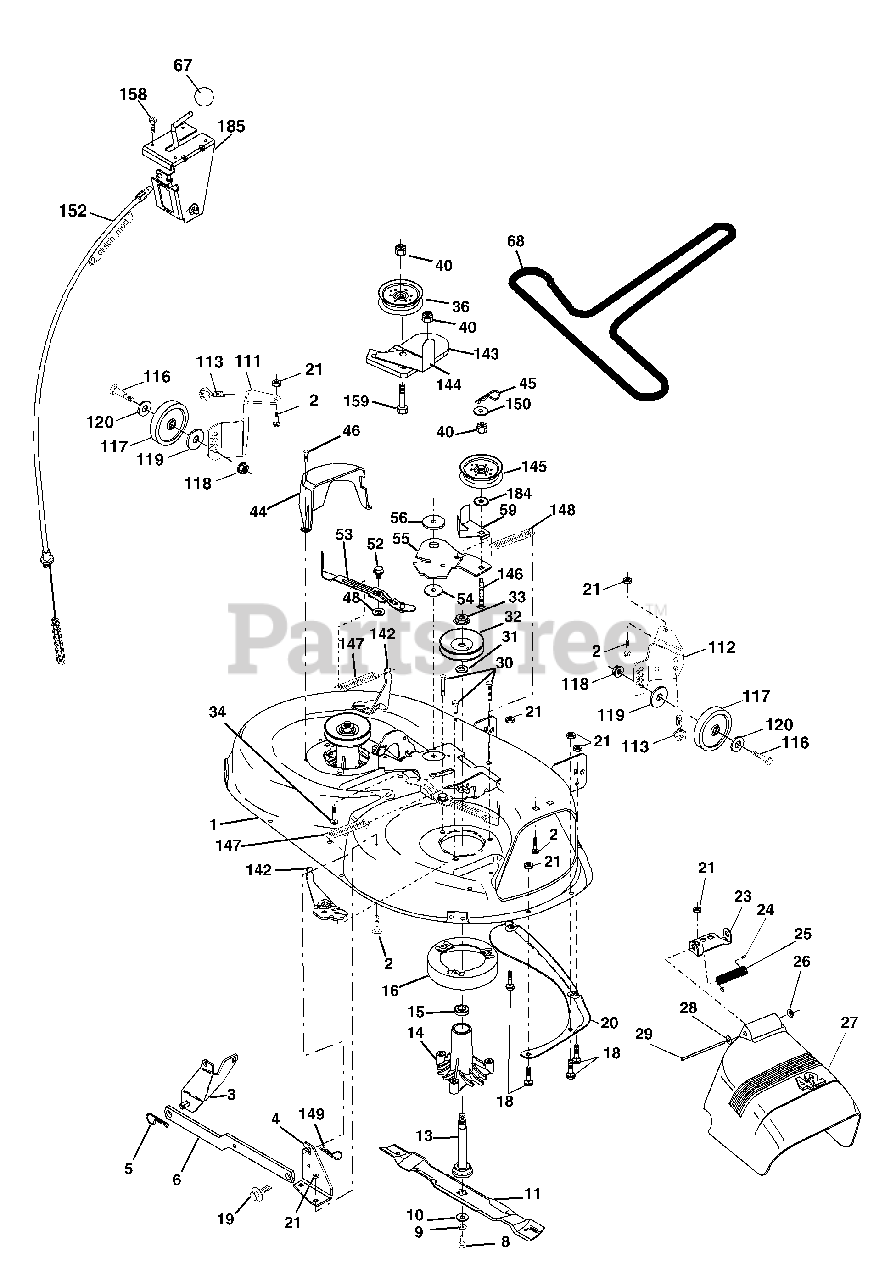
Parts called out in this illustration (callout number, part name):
1	Mower Deck Assembly, 42"
2	Bolt
3	Bracket Asm Fr. Sway Bar 3/42
4	Bracket Asm Deck 42" Sway Bar
5	Retainer Spring
6	Bar Sway Deck
8	Bolt 3/8-24 x 25 Gr. 8 patched
9	Washer, Lock
10	Washer, Hardened
11	Blade, 42" Mulching Std
11	Blade, 42" Mulching Premium
11	Blade, 42" Hi-Lift
13	Shaft Assembly, Mandrel, Vented
14	Housing, Mandrel, Vented
15	Bearing, Ball, Mandrel
16	Stripper, Mandrel Deck
18	Bolt, Carriage 5/16-18 x 5/8
19	Bolt, Shoulder
20	Baffle, Vortex
21	Nut
23	Bracket, Deflector Mower 42"
24	Cap, Sleeve 80 x 112 Blk Mower
25	Spring, Torsion, Deflector 2 52
26	Nut, Push Phos & Oil
27	Shield, Deflector 42" Blk
28	Washer 11/32 x 5/8 x 16 Ga.
29	Rod, Hinge 42" 6 75 W/G
30	Screw Thdrol Washer Head
31	Washer, Spacer Mower Vented
32	Pulley, Mandrel
33	Nut, Toplock 9/16 Flange
34	Bolt
36	Pulley, Idler, Flat
37	Washer 13/32 x 13/16 x 16 Ga.
44	Guard, Mandrel, LH
45	Retainer
46	Screw, Thdrol 1/4-20 x 5/8 T
48	Washer, Hardened
52	Bolt, Shoulder 5/16-18 unc
53	Arm Assembly, Pad, Brake
54	Washer, Hardened
55	Arm, Idler
56	Spacer, Retainer
59	Guard TUV Idler
67	Knob
68	V-Belt, 42" Mower
111	Bracket Wheel Gauge LH
112	Bracket Wheel Gauge RH
113	Bolt 5/16-18
116	Bolt Shoulder
117	Wheel Gauge
118	Nut Centerlock 3/8-16
119	Washer 3/8 x 7/8 x 14 Ga.
120	Washer 17/32 x 15/16 x 12 Ga.
142	Arm Spring Brake Mower
143	Bracket Arm Idler 42"
144	Keeper Belt 42" Clutch Cable
145	Pulley Idler Flat
146	Bolt Carriage Idler
147	Spring Extension
148	Spring Return Idler
149	Retainer Spring Yellow
150	Washer 9/32 x 3/4 x 10 Ga.
152	Clutch Cable 42"
158	Screw Hex Thd Cut 1/4-20 x 1/2
159	Bolt Rdhd Sqn 3/8-16 unc x 1-3/4
184	Washer 13/32 x 7/8 x 10 Ga.
185	Head Asm Cable Clutch
